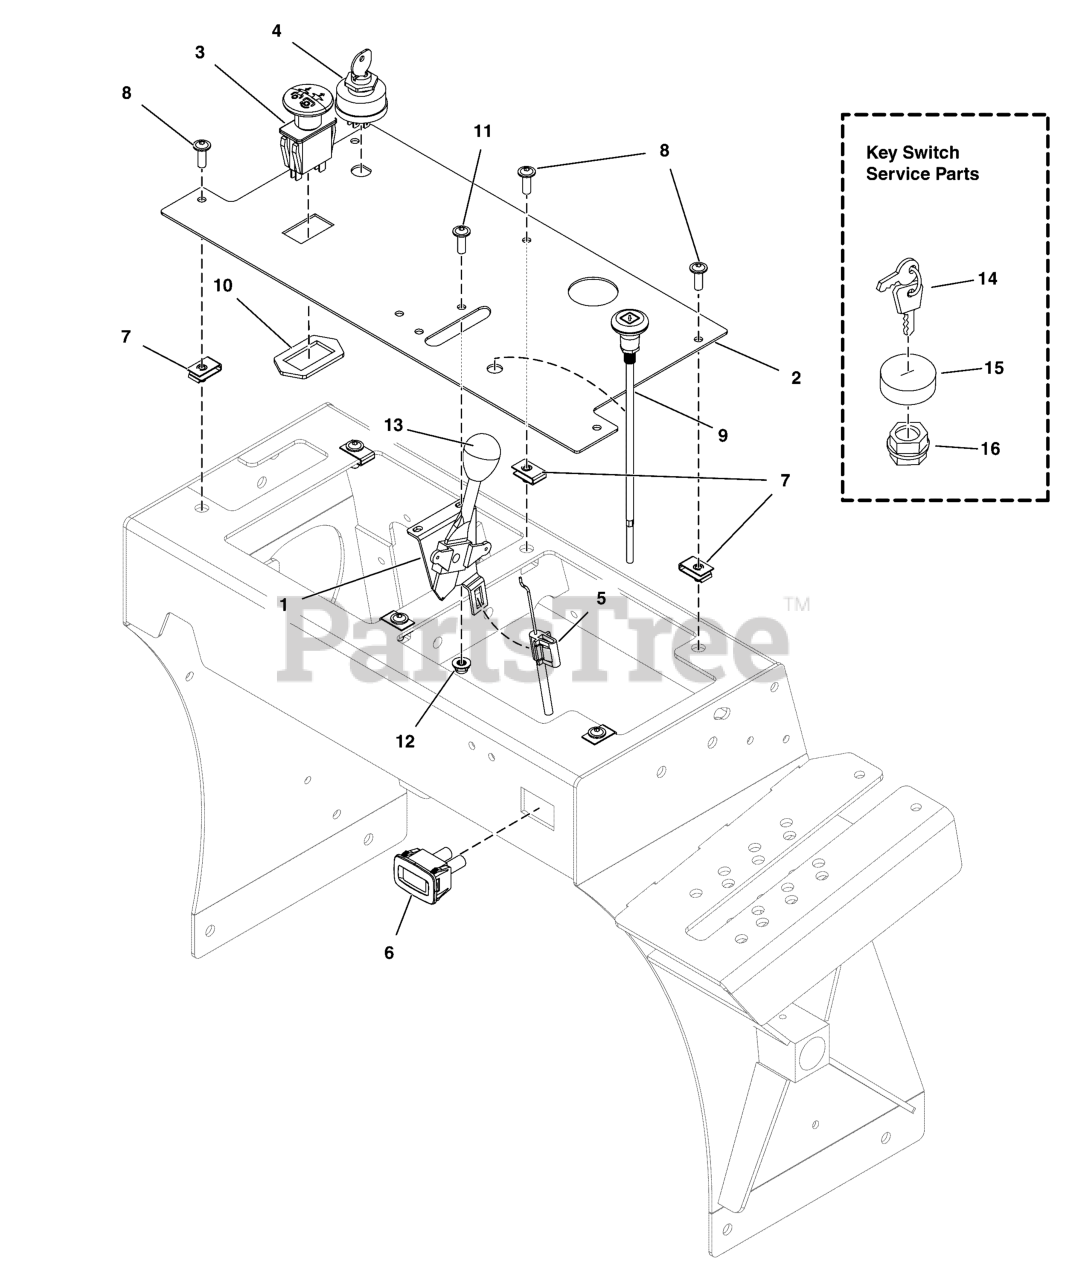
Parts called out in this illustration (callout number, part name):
1	LEVER, HEAVY DUTY, THROTTLE CONTROL
2	DASH PANEL W/DECALS, SRSZ2 (5415654A)
3	PTO SWITCH, MOMENTARY, SMALL KNOB
4	SWITCH, IGNITION, 6 POST
5	CABLE, THROTTLE, 40"
6	HOUR METER
7	BODY CLIP, 1/4-20 X 1/2" DEEP
9	CABLE, CHOKE CONTROL, 43.5"
10	RING, SWITCH RETAINER
11	SCREW, #10-24 X 1/2" ROUND PHILLIPS
12	NUT, Hex, Nylon Lock, #10-24
13	THROTTLE CONTROL HANDLE/KNOB
14	KEY, IGNITION MOLDED SET
15	COVER, PLASTIC, SNAP ON
16	PLASTIC NUT
